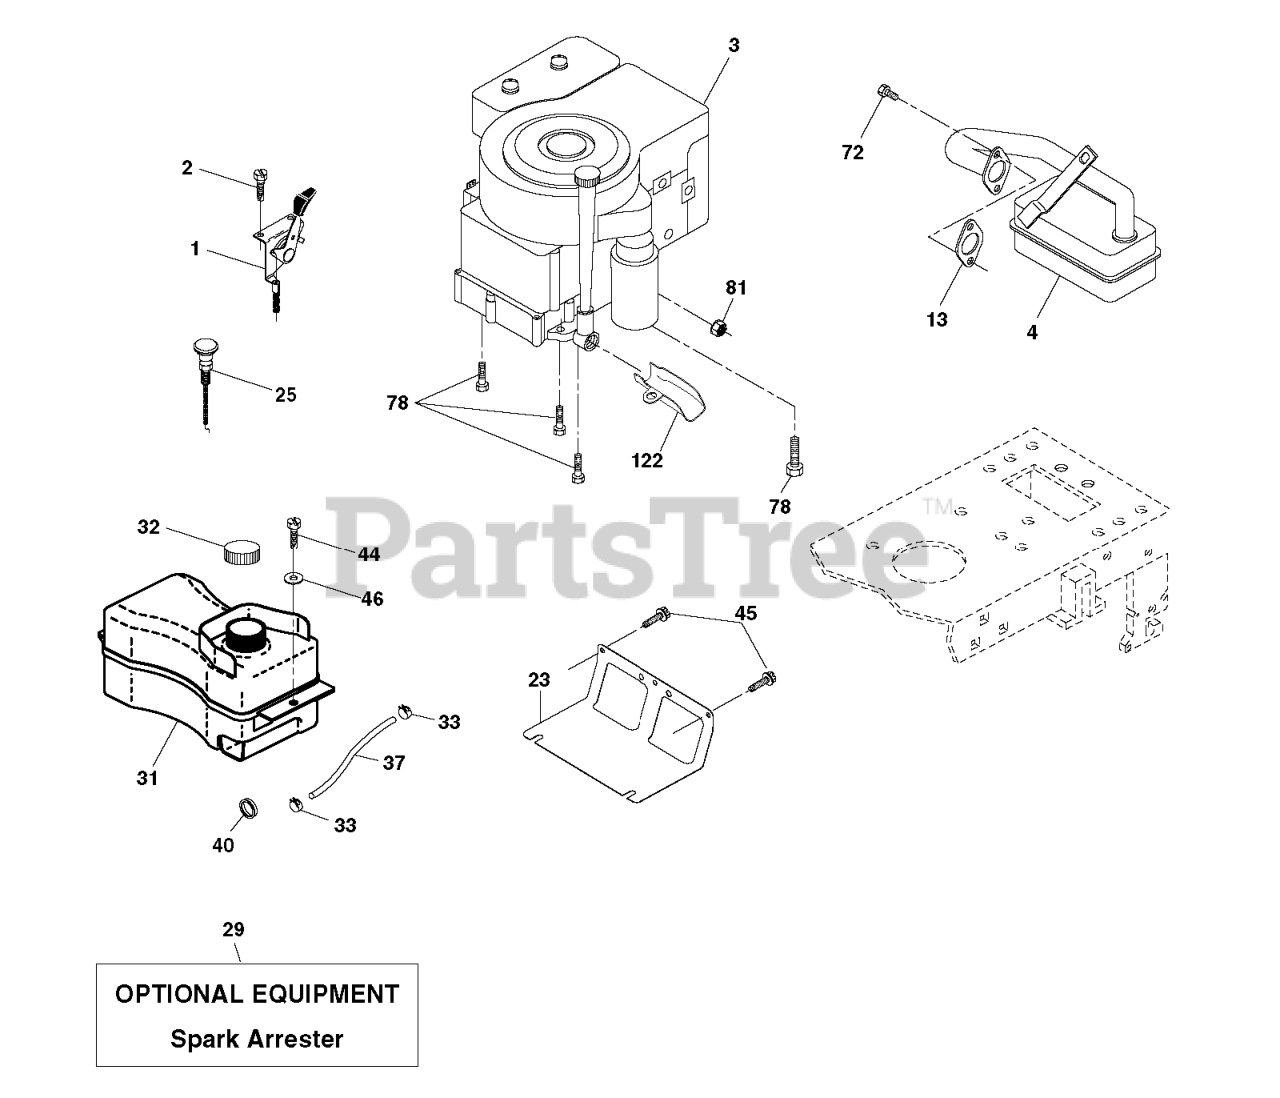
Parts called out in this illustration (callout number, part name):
1	CONTROL.THROTTLE/CHOKE.BLACK
2	SCREW
4	MUFFLER.B&S.MODEL.21.11HP.OHV
13	REPL BY 532 27 22-93
23	SHIELD.BROWNING.DBR.GUARD
25	KNOB.ERGO.EXTENDED.RED (1 2)
29	KIT.SPARK ARRESTOR 794945 B&S
32	CAP.FUEL.2.25"VENTED"
33	HOSE CLAMP
37	LINE.FUEL.20
40	BUSHING.SNAP.NYL.BLK.
44	SCREW HEXWSHR 1/4-20X3/4
45	SCREW, 3/8-16X3/4
72	SCREW.SOCKET HD.5/16-1
78	SCREW.3/8-16
81	NUT
122	EXTENSION DRAIN OIL
